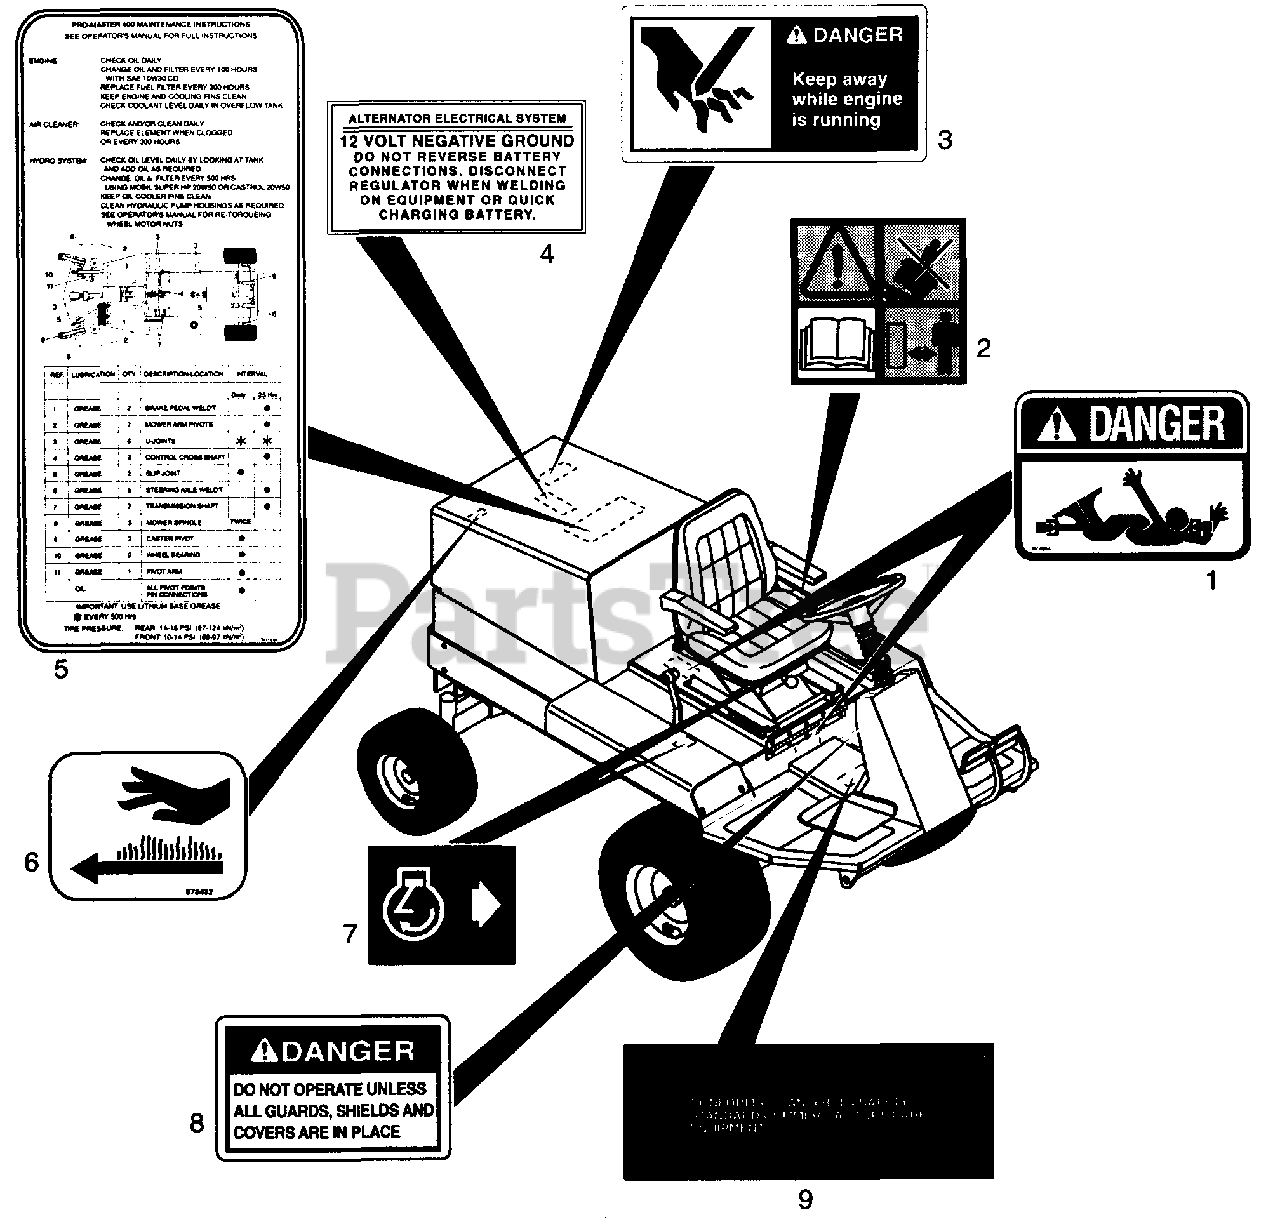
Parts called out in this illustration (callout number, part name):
1	Decal-PTO Danger
2	Decal-International Symbols
3	Decal-Danger Hand
4	Decal-E-System Warning
5	Decal-G-Series Maintenance
6	Decal-Hot Surface
7	Decal-Start
8	Decal-Belt Installation
9	Decal-ANSI
